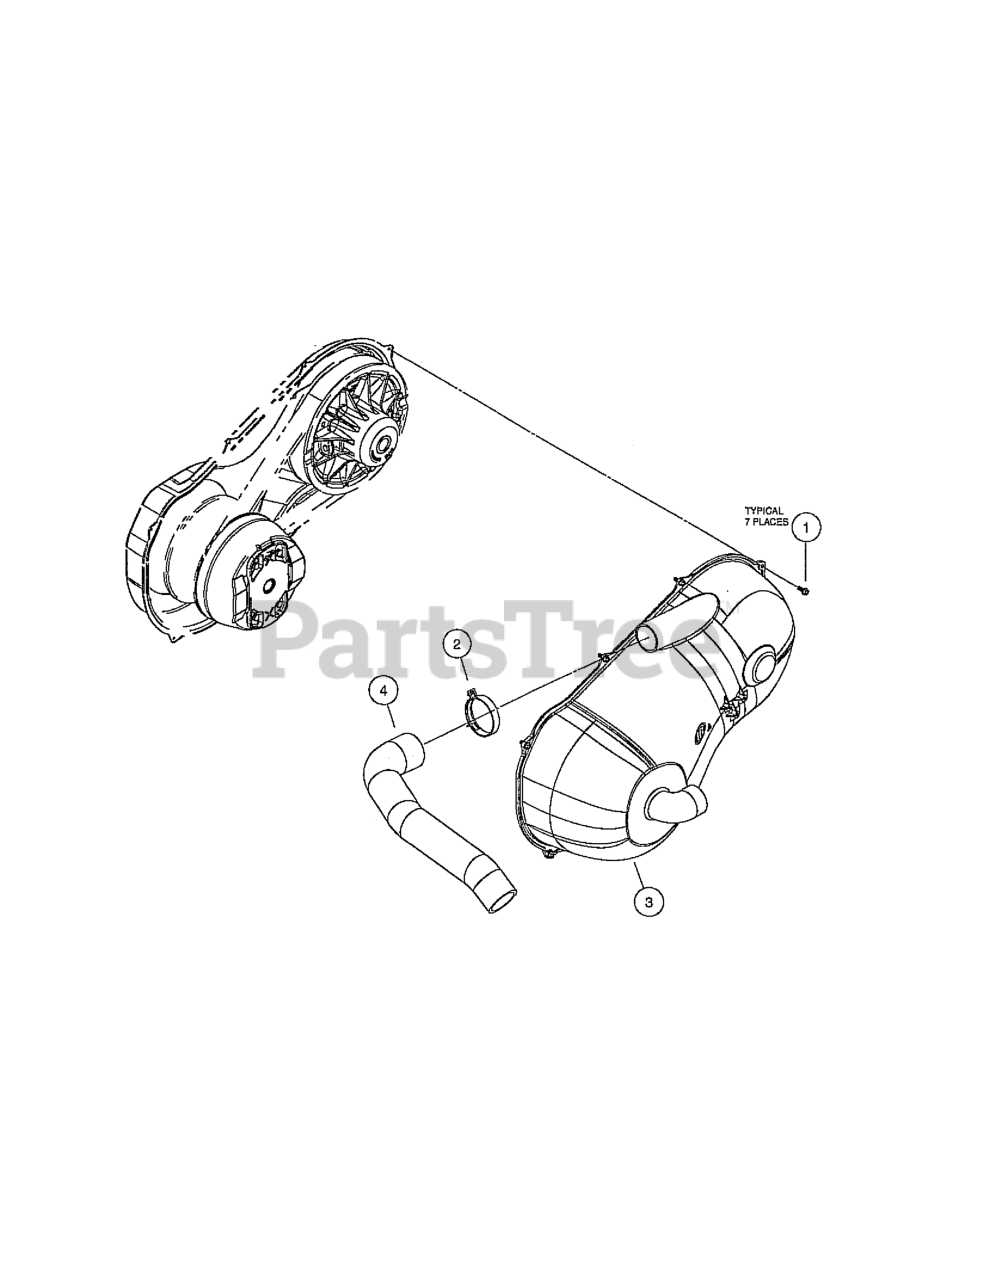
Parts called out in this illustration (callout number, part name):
1	SCREW, M6 X 16 TT HX FL HD
2	CLAMP, HOSE, CTB 64MM
3	COVER, CVT OUTER
4	HOSE, OUTLET, COVER, CVT
